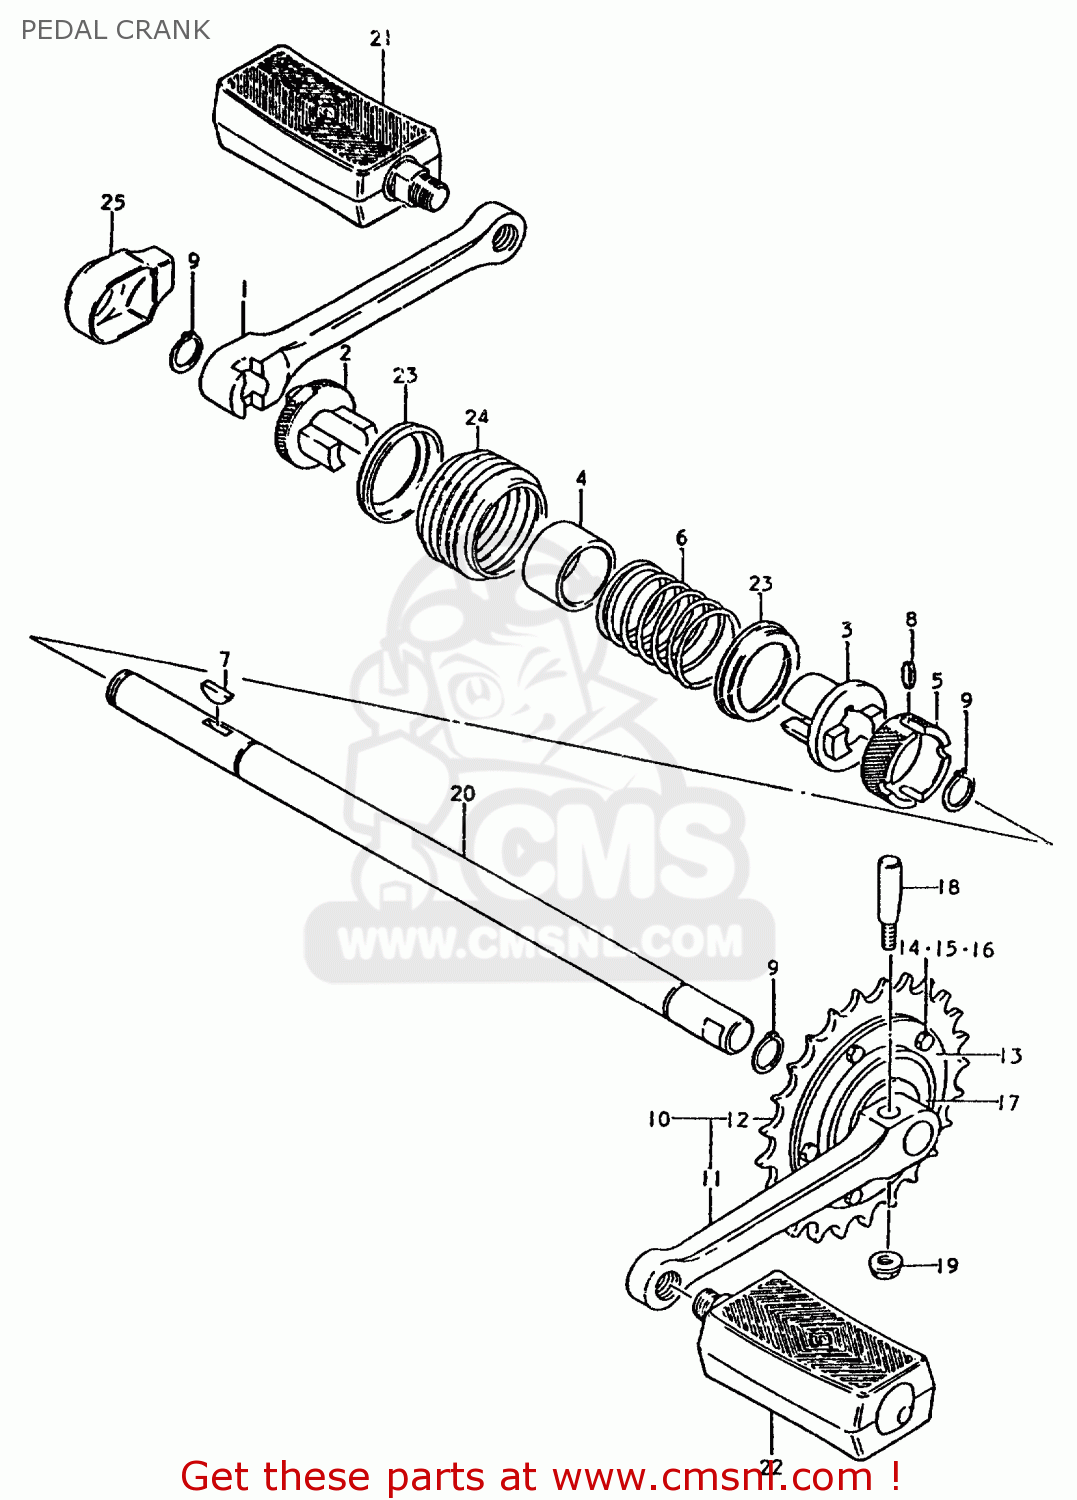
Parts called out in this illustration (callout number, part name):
1	CRANK, RH
2	DOG, OUTER
3	DOG, INNER
4	SLEEVE, CRANK
5	STOPPER, DOG
6	SPRING
7	KEY
8	SPRING PIN
9	CIRCLIP,16MM
10	GEAR CRANK ASSY
11	CRANK, LH
12	SPROCKET
13	SPACER
14	NUT 6MM
15	LOCK WASHER
16	BOLT(6X14)
17	FREE WHEEL
18	PIN
19	NUT
20	SHAFT, CRANK
21	PEDAL ASSY, RH
22	PEDAL ASSY, LH
23	COLLOR, DUST SEAL CRANK
24	DUST SEAL, CRANK
25	CAP, CRANK
